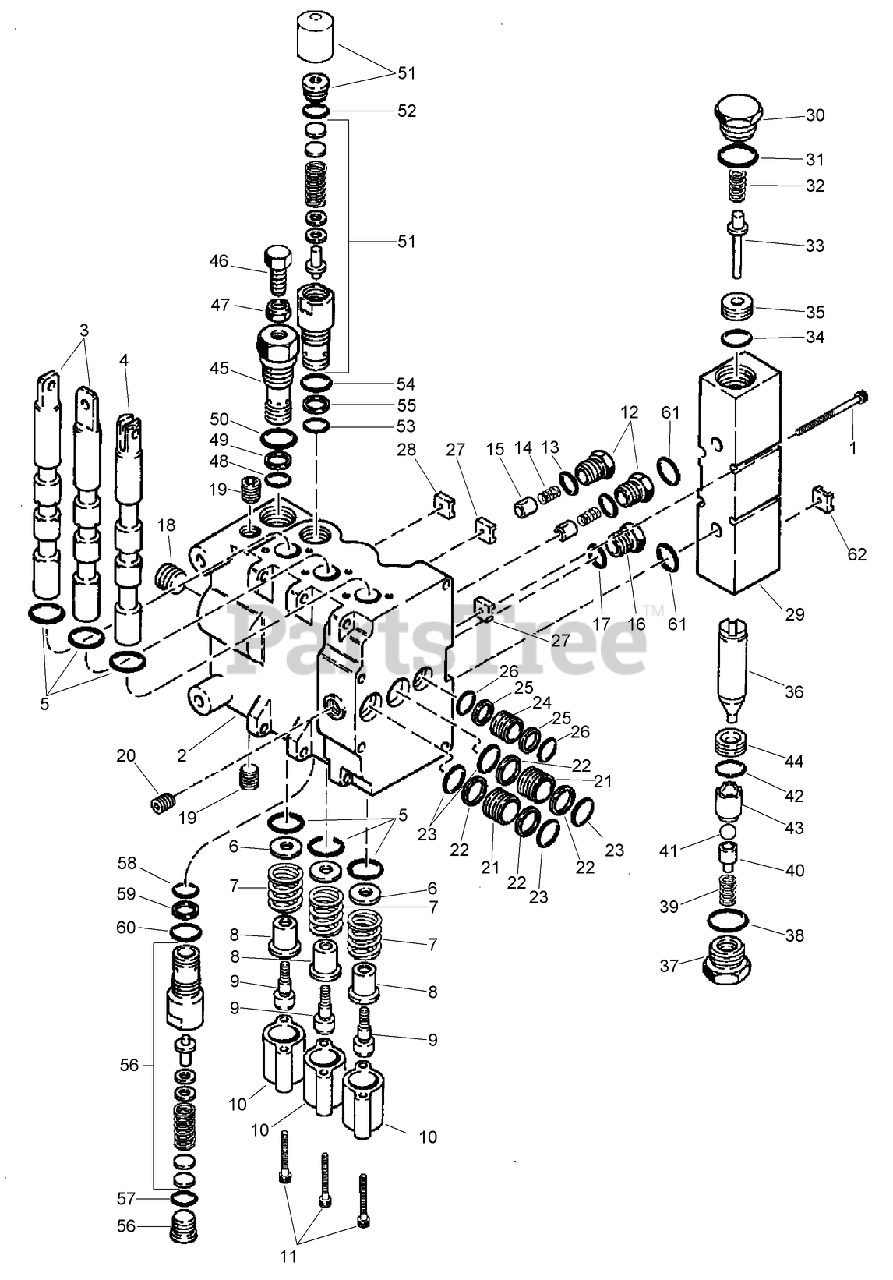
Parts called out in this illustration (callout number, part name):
2	BODY-inlet section
3	SPOOL-dual control
4	SPOOL-stabilizer
6	WASHER-FLAT
7	SPRING-RETURN
8	SPACER-spring
9	BOLT-shoulder, special
10	Cap-End
12	PLUG ASM
14	SPRING-poppet
15	Poppet-Load Check
16	LOAD CHECK KIT
18	PLUG-HEX SOCKET, PIPE
19	PLUG
20	PLUG-seal
22	RING-backup, sleeve O-ring
25	RING-BACKUP
29	BODY-pilot check
31	O-RING
32	SPRING
33	POPPET
34	O-RING
35	SEAT-PILOT
36	PLUNGER
38	O-RING
41	BALL-STEEL
43	RETAINER
44	SEAT-PILOT
45	Valve-Relief
49	RING-BACKUP
51	Valve-Relief
54	O-RING
55	RING-BACKUP
56	Valve-Relief
59	RING-BACKUP
60	O-RING
62	ORIFICE
